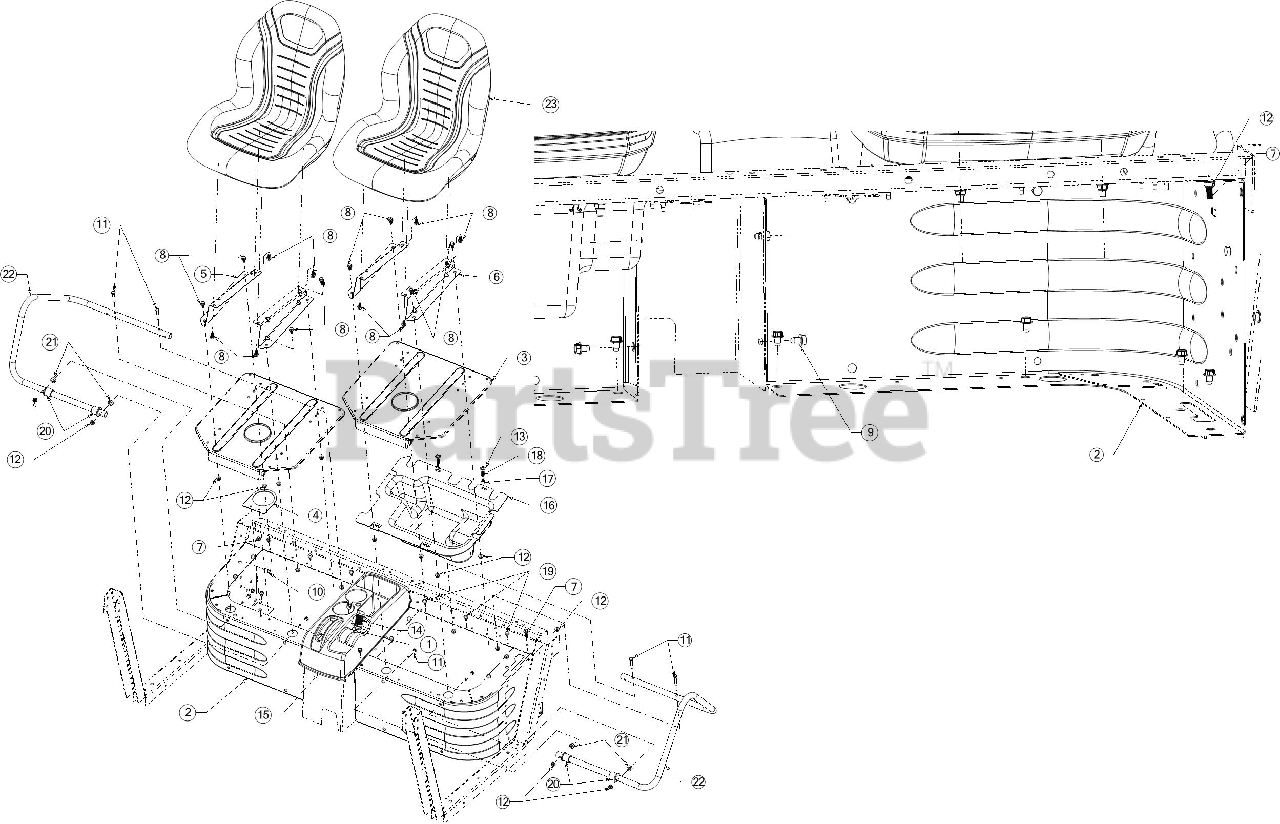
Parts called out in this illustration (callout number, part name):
1	DIFF LOCK LEVER ASSEMBLY
2	UV SEAT BOX ASSEMBLY
3	SEAT PLATE ASSEMBLY
5	SEAT TILT MOUNT BRACKET (RH)
6	SEAT TILT MOUNT BRACKET (LH)
7	SCREW 5/16-18 x 1 GR5
8	HEX SCREW 5/16-18 x .625 GR5
9	SCREW 5/16-18 x .500
10	SCREW 5/16-18 x .75 GR5
11	SCREW 5/16-18 x 1.75 GR5
12	FLANGE LOCK NUT 5/16-18
13	1/4 TURN PANEL HANDLE
14	BRAKE HANDLE GRIP
15	SEAT CONSOLE
16	SEAT BOX TRAY
17	SPRING CLIP
18	COMPRESSION SPRING
19	BUMPER, .62 DIA x .3
20	FLANGE BEARING
